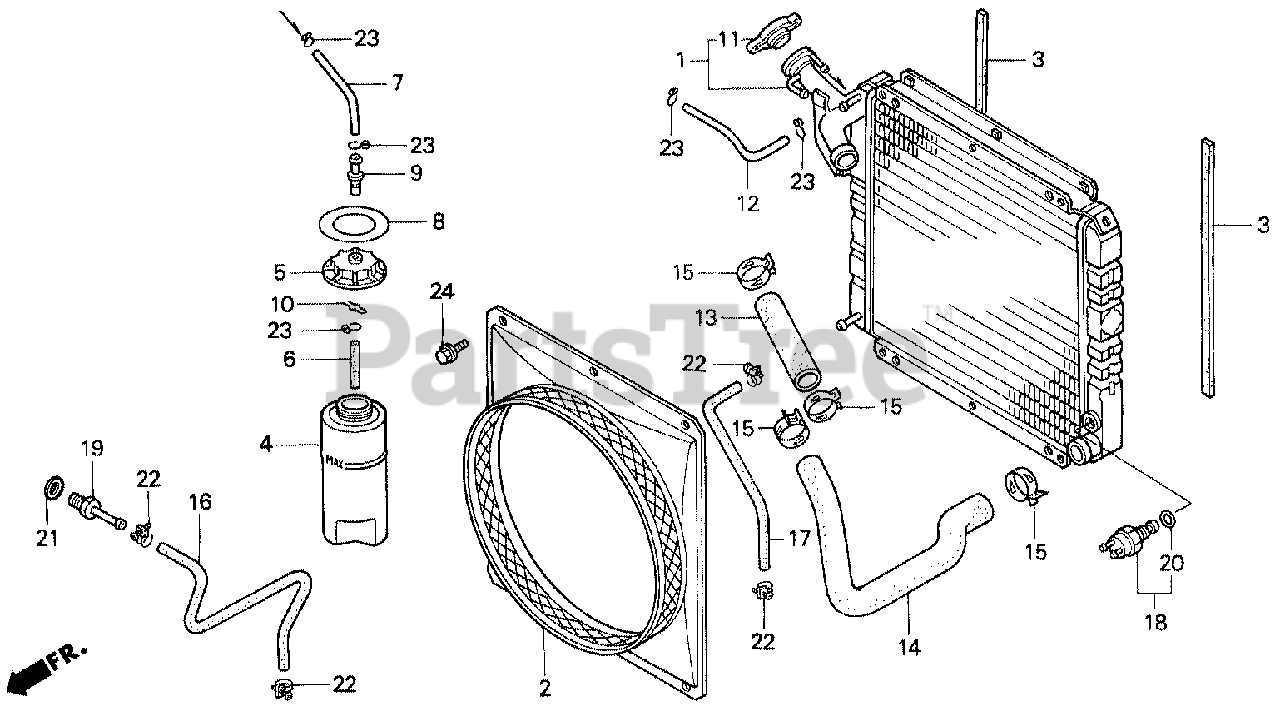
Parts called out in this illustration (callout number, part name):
3	SEAL, RADIATOR
4	TANK, RESERVE
5	CAP, RESERVE TANK
6	HOSE, RESERVE TANK
7	TUBE, RESERVE TANK
8	MARK, RESERVE TANK
9	JOINT, RESERVE TANK
10	CLIP, RESERVE TANK JOINT
11	CAP, RADIATOR FILLER (TOYO)
11	CAP, RADIATOR FILLER
12	TUBE, RADIATOR BREATHER
13	HOSE, WATER (UPPER)
14	HOSE, WATER (LOWER)
15	CLIP, WATER HOSE
16	TUBE, WATER DRAIN (A)
17	TUBE, WATER DRAIN (B)
18	SWITCH, THERMOSTAT
19	BOLT, WATER DRAIN PLUG
20	O-RING (13.5X1.4)
21	WASHER, DRAIN PLUG (12MM)
22	CLIP, TUBE (D13)
23	CLIP, TUBE (C11)
24	BOLT, FLANGE (6X12)
